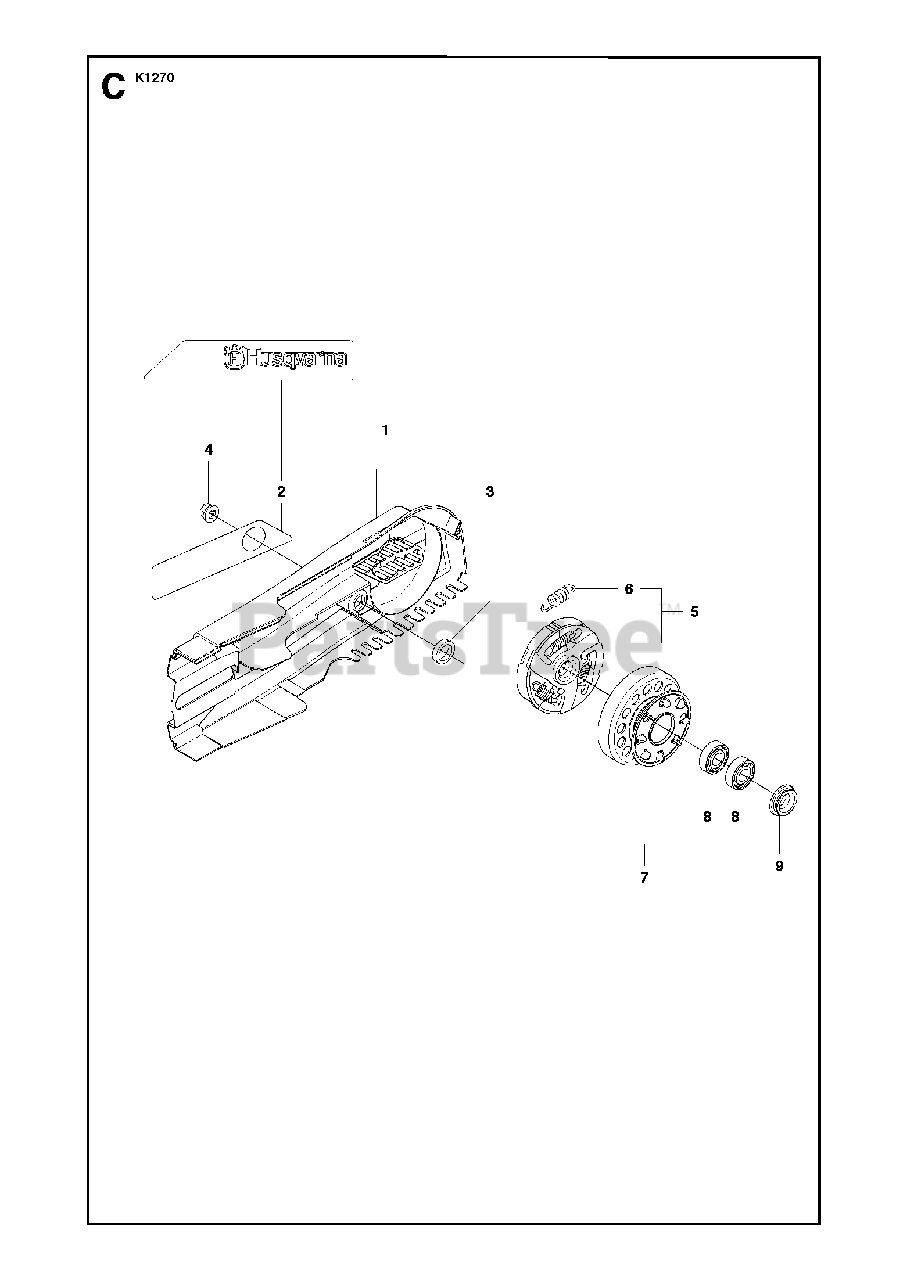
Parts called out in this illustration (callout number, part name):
1	BELT GUARDIncl. 2, 3
3	SPACING SLEEVE
5	CLUTCH ASSYIncl. 6
6	CLUTCH SPRING
7	DRIVING PULLEY ASSY"14"". Incl. 8"
7	DRIVING PULLEY ASSY"16"". Incl. 8"
8	BALL BEARING
